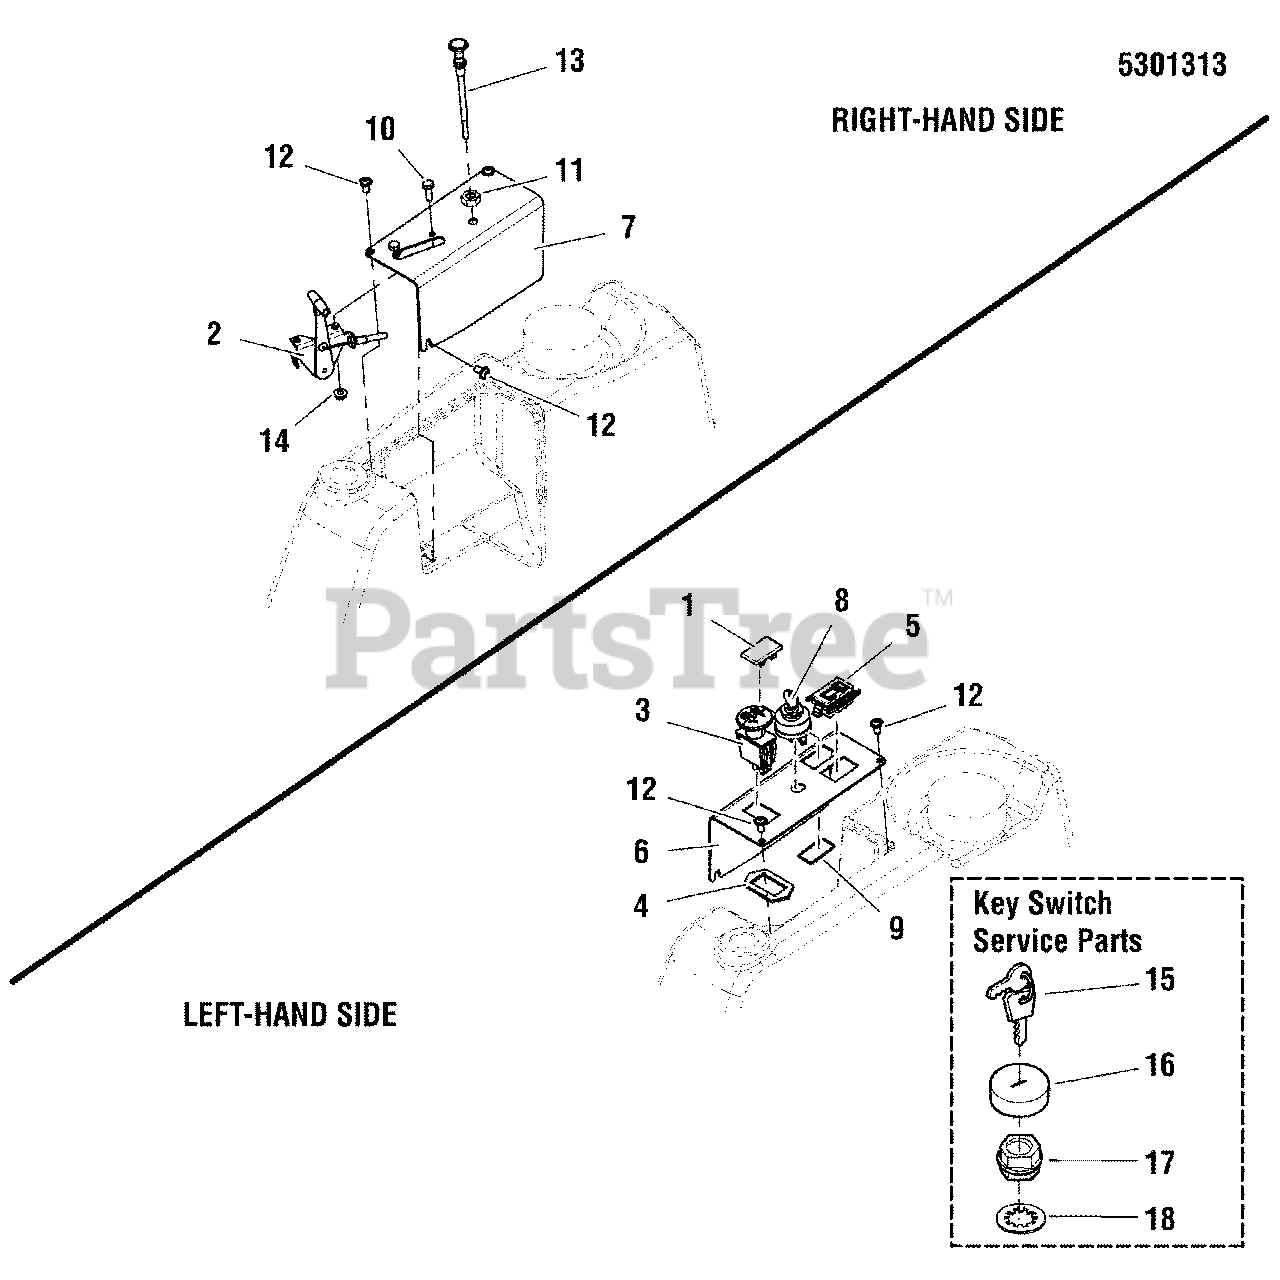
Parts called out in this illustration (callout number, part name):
1	PLUG, .820X1.44 HOLE, BLACK PLASTIC
2	CABLE, THROTTLE CONTROL, 38
3	SWITCH, BLADE ENGAGEMENT
4	RING, SWITCH RETAINER
6	CONTROL PANEL, LEFT - BLK
7	CONTROL PANEL, RIGHT - BLK
8	SWITCH ASSEMBLY, Ignition Indak No Keys/Hdwr
9	O-RING, 7/8" ID X 1/16" W
10	CAPSCREW, HEX HEAD, 1/4-20 X 5/8
11	NUT, 3/8-24 Hex Jam
12	SCREW, ALLEN HEAD 1/4-20 X .500 ZINC PHOS
13	CABLE, CHOKE CONTROL, 39.5"
14	NUT, 1/4-20 Hex Nylock Flange
15	KEYS, Blister Pk (KIDS+MWRS DON'T MIX) English/Spanish (set of two, one coated)
16	COVER, For Ignition Switch, Plastic
17	NUT, 5/8-32 Hex Flange (Ignition Switch Die Cast)
18	LOCKWASHER-INTERNAL TOOTH, .625 THIN BLK (SV)
